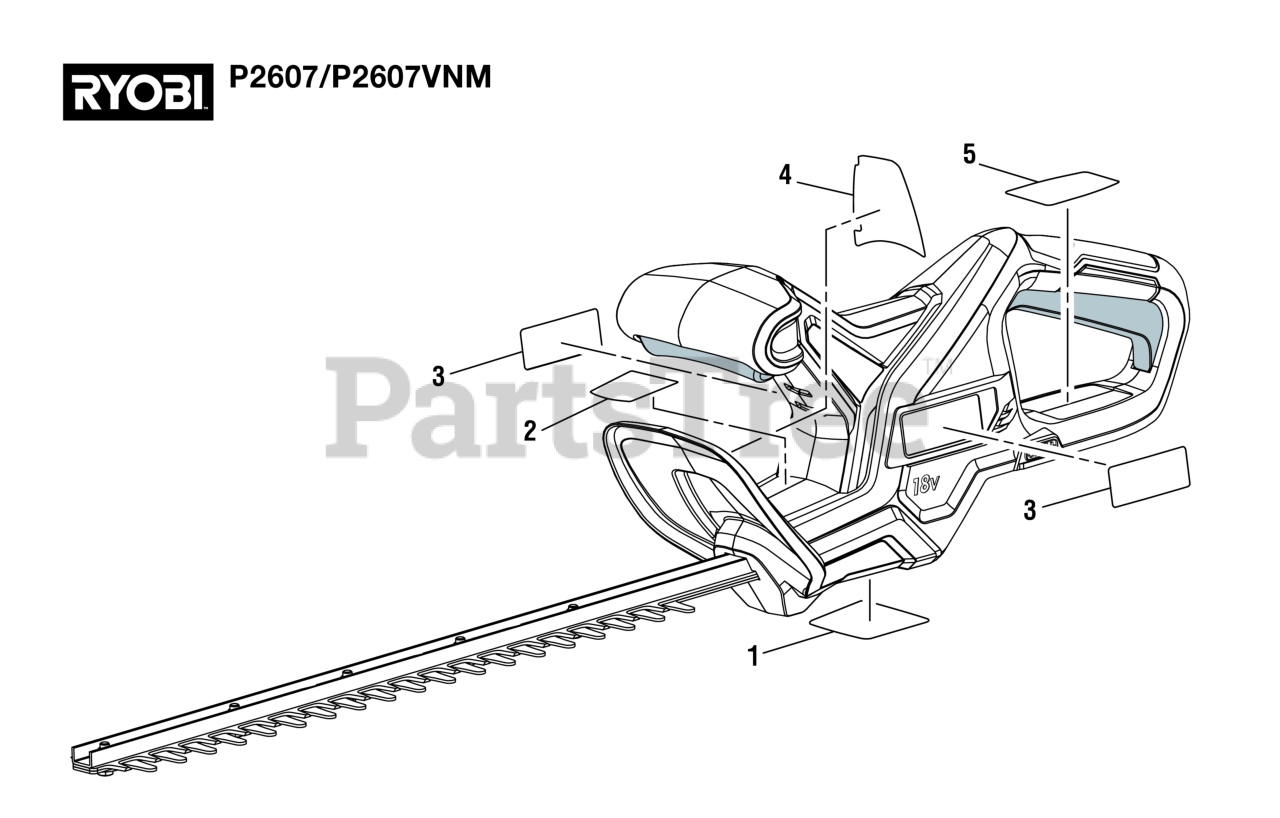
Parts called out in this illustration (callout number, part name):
1	Data Label
2	Warning Label (Spanish)
3	Logo Label
4	Danger Warning Label (English/French/Spanish)
5	Warning Icons Label
